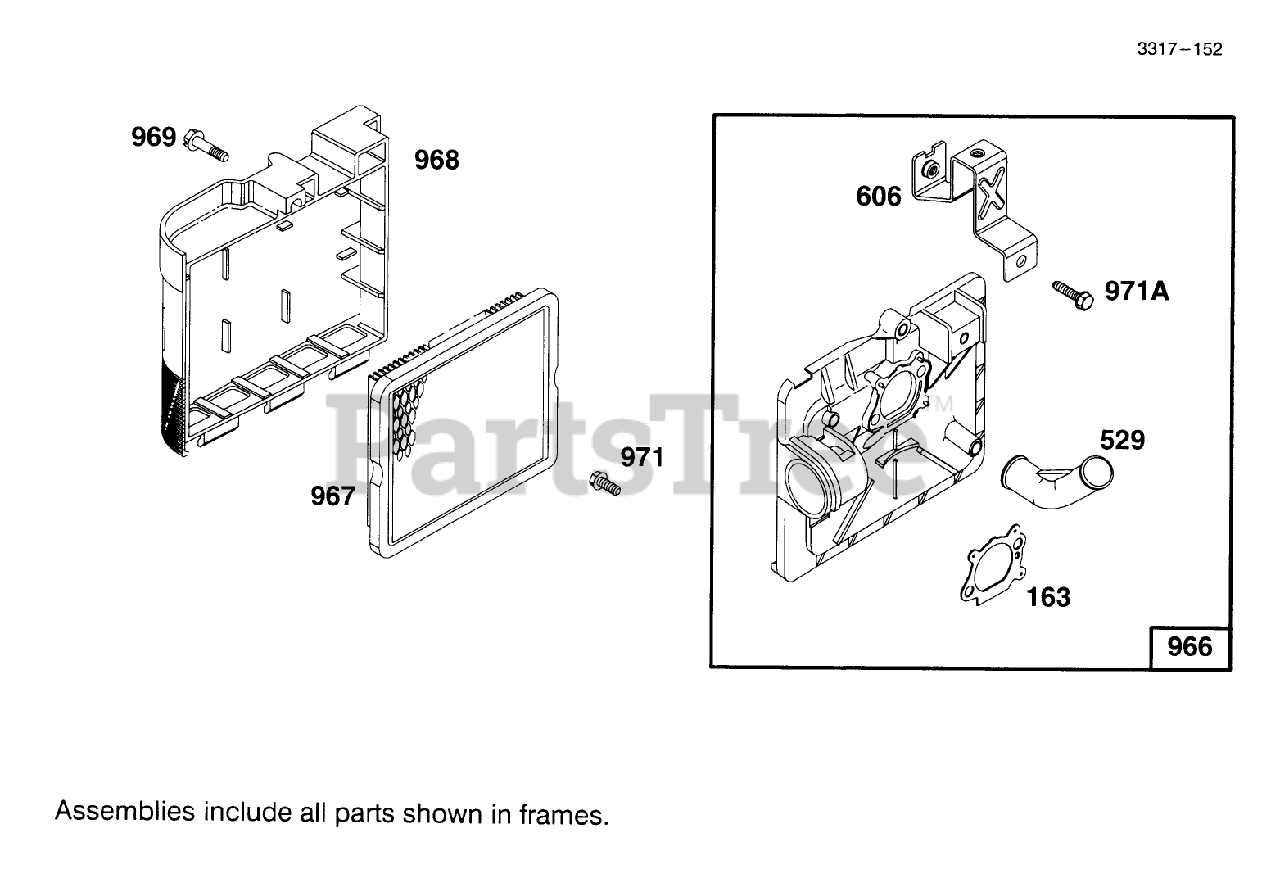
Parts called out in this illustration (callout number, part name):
163	Gasket-Cleaner, Air
529	Grommet
606	Strap-Bracket
966	Base-Primer, Air Cleaner
967	Filter-Air Cleaner, Cartridge
968	Air Cleaner Cover
969	Screw-Cover Mt.
971	Screw-Air Cleaner
971A	Screw-Hex.
